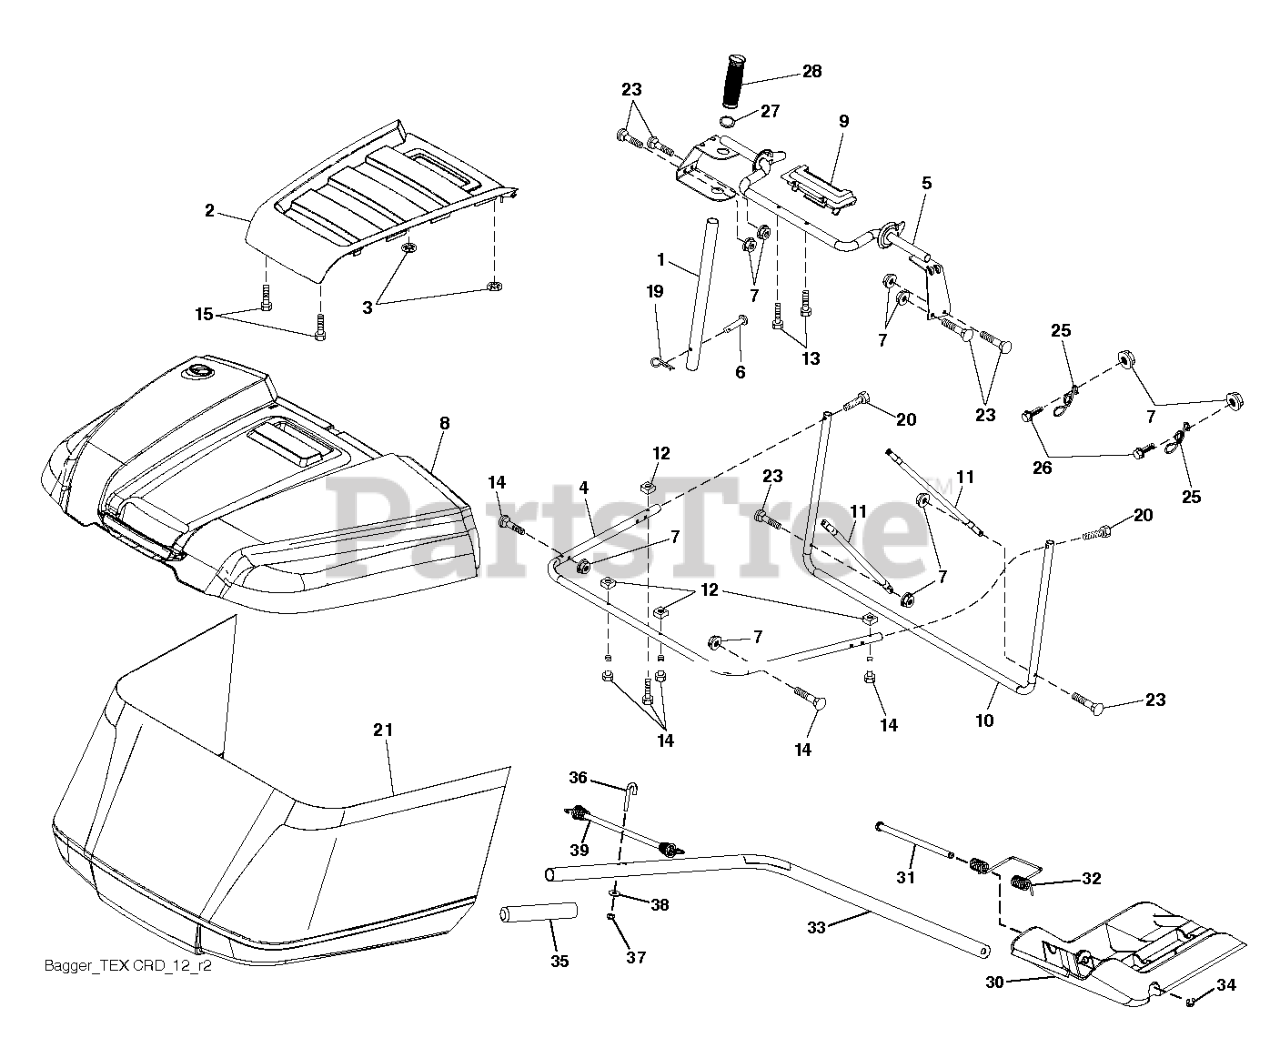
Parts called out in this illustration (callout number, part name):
1	TUBE.HANDLE.BAGGER.CRD/SRD.BLA
2	APPLIQUE.TOP.BAG.SRD.ORANGE
3	NUT.PUSH.156
4	SUBASM.TOP.TUBE.TEX.CRD
5	FRAME.ASM.TOP.BAGGER.SRD
6	RIVET,DRILLED
7	NUT T
8	BAGGER.TOP.SRD.APPLIQUE
9	INSERT.HANDLE.BAGGER.(2 2)
10	FRAME FRAME.FRONT.TEX.CRD
11	BRACE BRACE SIDE TUBE
12	NUT.SQUARE.1/4
13	SCREW.1/4X1.150.HXWSH
14	BOLT.SHOULDER.HX.WSH.1/4X1.150
15	SCREW,#8.FLAT.HEAD.DRILL.TIP
19	PIN.COTTER.5/16.BOW TI
20	SCREW.HEXCAP.1/4-20X1.375(2 2)
21	BAG SUBASM. TEX CRD GEN 2 HUSQ
25	SPRING.LATCH.BAGGER.SRD
26	SCREW HEX CRT
27	RB GROMMET.RUBBER.SRD
28	GRIP.HANDLE.BLACK
30	PLUG PLUG
31	PIN PIN.HINGE
32	SPRING SPRING DOUBLE TORSION
33	SHAFT SHAFT TEX CRD MULCH PLU
34	E-RING.5/16"
35	GRIP GRIP MULCH PLUG HAND
36	BOLT BOLT J
39	BUBGEE BUBGEE TEX CRD
